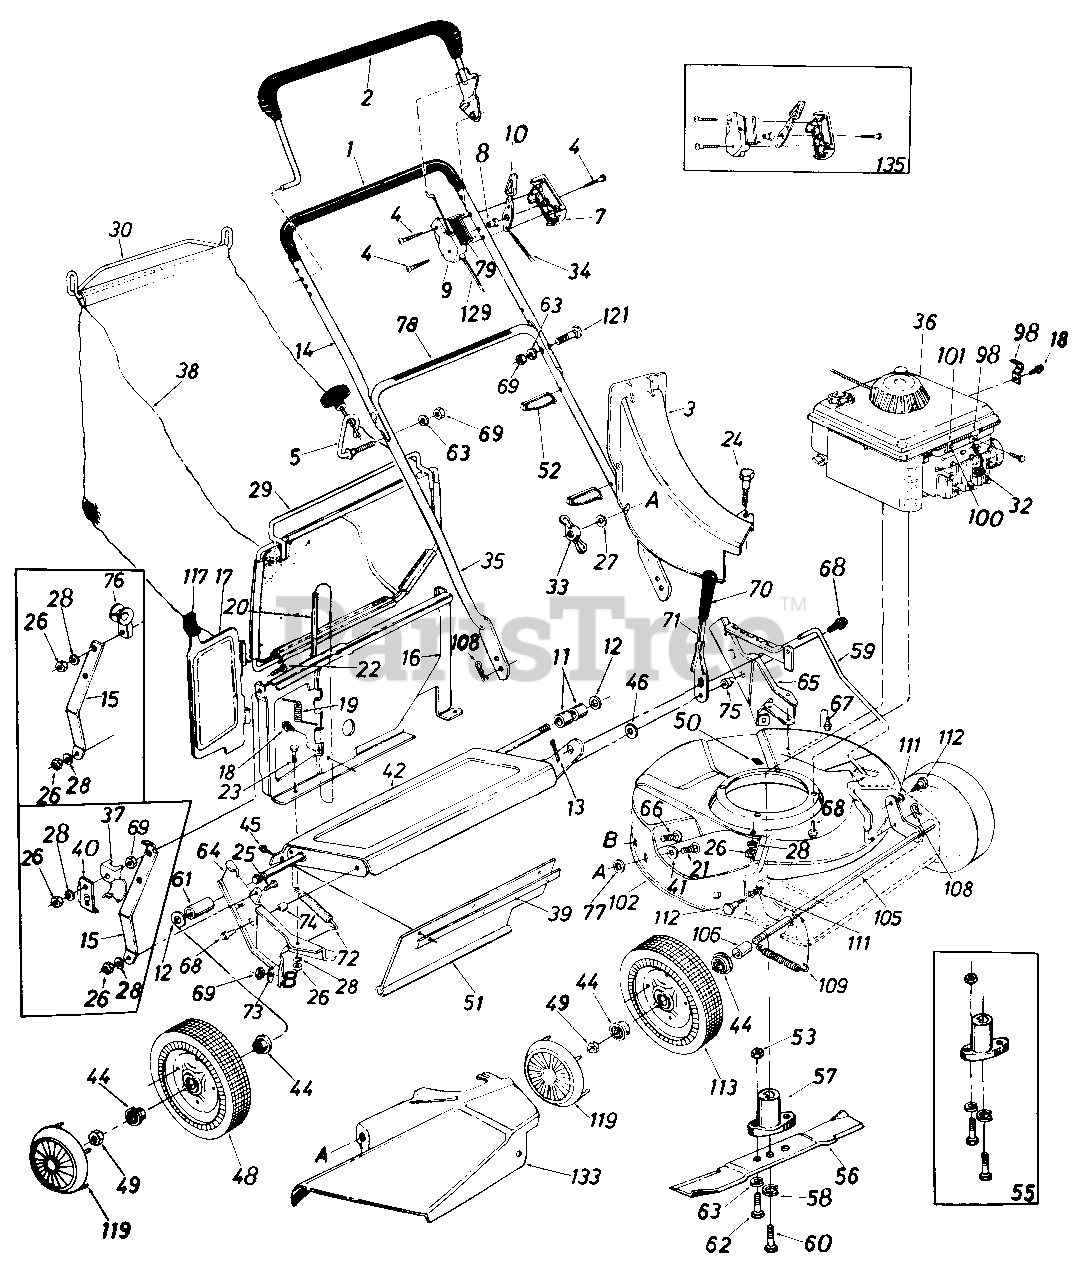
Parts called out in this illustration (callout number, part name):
1	Grip
2	Control Handle Ass'y.-L.H.
3	Top Discharge Chute Ass y.
4	Truss Mach. Scr. #12 x 1.50" Lg.
5	Rope Guide Bolt
7	Control Panel Half
8	Control Disc Pin
9	Clutch Panel Half
10	Throttle Control Lever
11	Spacer.526" I.D. x .690" O.D. x .640" Lg.
12	Fl-Wash. .510" I.D. x .75"
13	Cotter Pin 3132" Dia. x .75"
14	Upper Handle-Chrome
15	Panel Support Brkt.
16	Top Catcher Panel
17	Top Door
18	Hex B-Tap Scr. #10 x .38"
19	Torsion Spring
21	Carriage Bolt 1/4-20 x .62"
22	Truss Mach. Scr. 1/4-20 x 1.0" Lg.
23	Hex Bolt 1/4-20 x .50" Lg.
24	Shoulder Bolt .312 Dia. x .18 Lg. Special
25	Hex Bolt 1/4-20 X .62" Lg.
26	Hex Nut 1/4-20 Thd.
27	Bell-Wash. 1/4" I.D.
28	L-Wash. 1/4" I.D.
29	Front Grass Catcher Frame
30	Grass Catcher Handle
32	Spark Plug Insulator
34	Throttle Control Wire 58"
35	Lower Handle-Chrome
36	Engine
37	Rope Guide Half
38	21" Top Discharge Grass Bag
39	Retaining Strip
40	Rope Retainer Spring Clip
41	Fl-Wash. .344" I.D. x .62"
42	Rear Axle Ass'y.
44	Flange Ball Bearing '/2" I.D.
45	Hex AB-Tap Scr. 1/4 X .62"
46	Fl-Wash. .38" I.D. x 1.0"
48	Rear Wheel Ass'y.-Comp. 8 x 1 .75
49	Hex L-Nut 1/2-20 Thd.
51	Rear Flap 3.75" x 17.30" Lg.
52	Cable Tie
53	Hex Nut 5/16-24 Thd.
55	Blade Adapter Kit
56	21" Blade
57	Blade Adapter
58	L-Wash. 3/8" I.D.-H.D.
59	Height Adj. Rod 19.42" Lg.
60	Hex Bolt 3/8-24 x 2.25" Lg. (Grade 5)
62	Hex Bolt 5/16-24 x 1.00" Lg. (Grade 5)
63	L-Wash. 5/16 I.D.*
64	R.H. Handle Wheel Brkt. Ass'y.
65	L.H. Handle Wheel Brkt. Ass'y.
66	Carriage Bolt 5/16-18 x .62"
67	Hex Wash. Hd. B-Tap Scr. 5/16-1 8
68	Hex Wash. Hd. TT-Tap Scr. 3/8-1 6
69	Hex Nut 5/16-18 Thd.
71	Height Adj. Lever
72	Extension Spring 3.8" Lg.
73	Bell-Wash. 5/16" I.D.
74	Spacer .385" I.D. x .502" O.D. x 270" Lg.
75	Shld. Spacer .500" Dia. x . 100
77	Bolt Retainer 1/4 X .50" O.D.
78	Instruction Label
79	Control Label
98	Casing Clamp
100	Hex B-Tap Scr. #10 x .62"
101	Casing Clamp
102	21" Deck Ass'y.
105	Front Axle Ass'y.
106	Sleeve .526" I.D. x .690" O.D. x .880" Lg.
108	Intern. Cotter Pin 5/16" Dia.
109	Extension Spring 3.2" Lg.
111	Intern. L-Wash. 3/8 I.D.
112	Shld. Bolt .623" Dia. x .425
113	Front-Wheel Ass'y. Comp. 7x 1.50
119	Hub Cap-Plastic
121	Curved Carr. Bolt 5/16-18 x 1.38" Lg.
129	Control Cable-43" Lg.
131	Side Chute Deflector Ass'y.
135	Kit-Control Housing Comp.
8112-000-7	Hardware Pack
